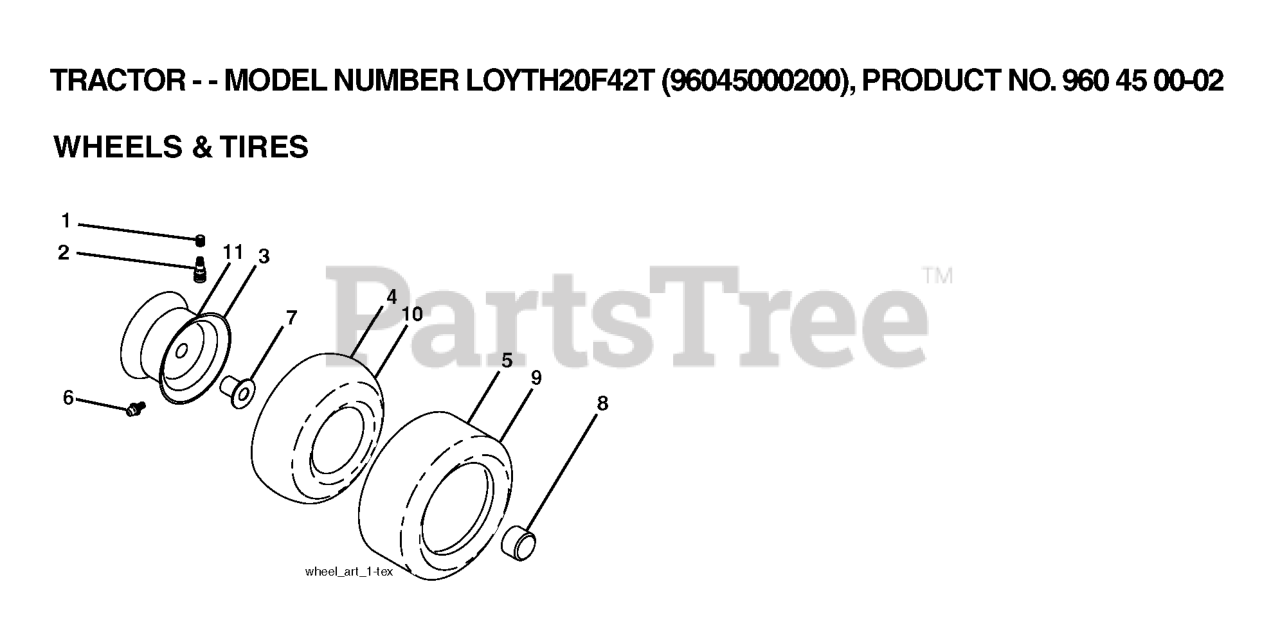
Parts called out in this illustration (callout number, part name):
2	VALVE STEM LT
3	RIM ASM 6" FRONT SILVER
4	TUBE.5.3/4.5/6
5	TIRE HEAVY DUTY
6	FITTING LT
7	BEARING T
8	CAP, AXLE BLK
9	TIRE.20X8-8.TURF.SAVER
10	TUBE
11	RIM ASM 8" REAR SILVER
